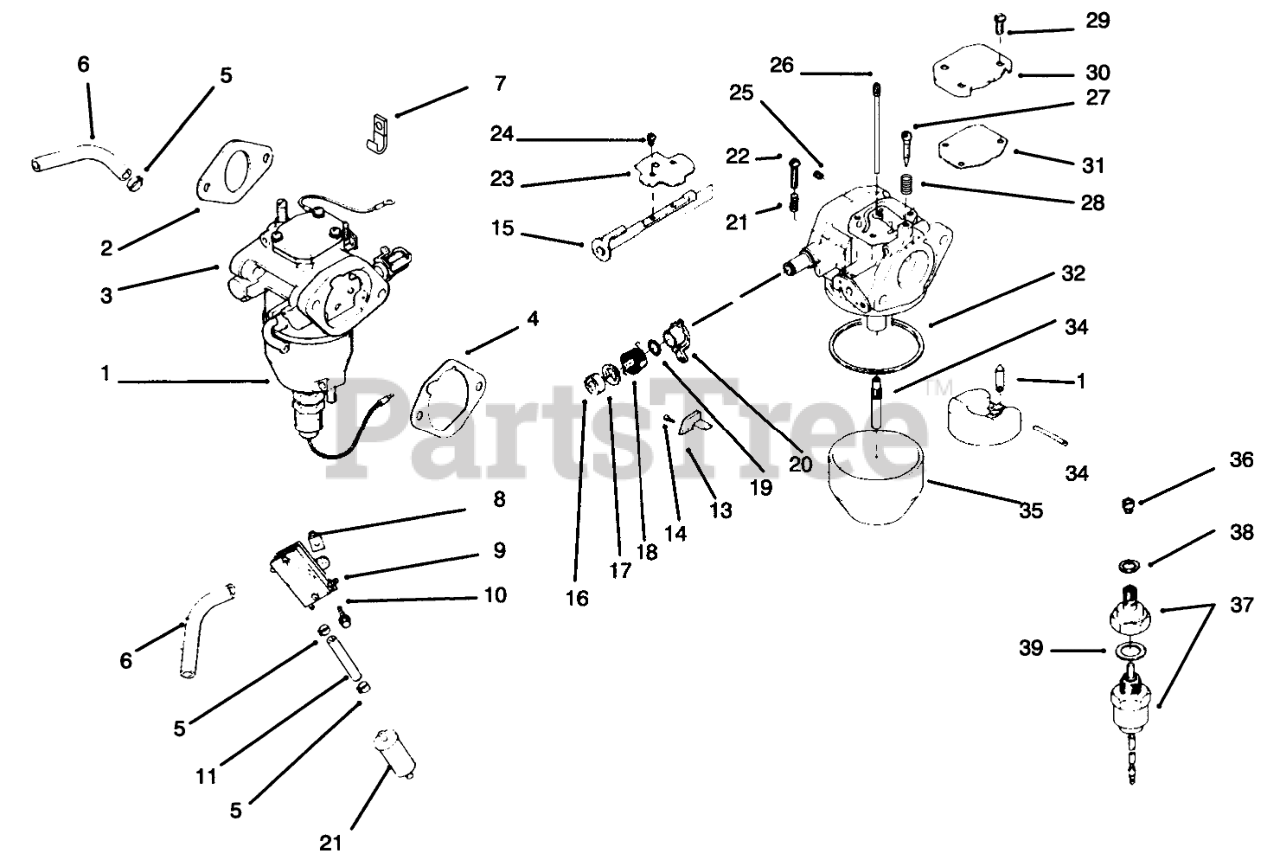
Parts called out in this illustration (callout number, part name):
1	Kit-Carburetor (Incl. Ref.#2-4)
2	Kit-Carburetor
3	Carburetor (Ref. Only) (Inc. Ref.15-39)
4	Gasket-A/C Base
5	Clamp-Hose
6	Line-Fuel 12"
7	Clamp
8	Nut
9	Pump-Fuel
10	Screw
11	Line-Fuel
12	Filter-Fuel
13	Bracket-Throttle Stop
15	Shaft-Choke
16	Washer
17	Collar-Coke
18	Spring-Choke Return
19	Ring-Choke Lever
20	Lever-Choke
21	Sprin-Throttle Screw
22	Screw-Throttle Adjust
23	Valve-Choke
24	Screw
25	Jet-Air Bleed
26	Jet-Slow
27	Screw
28	Spring-idler Screw
29	Screw
30	Cover-Passage
31	Gasket-Passage Cover
32	Gasket-Float Chamber
33	Kit-Float Repair
34	Nozzle-Main
35	Chamber-Float
36	Jet-Main
37	Kit-Solenoid Valve (Incl. Ref. #38-39)
38	Gasket-Chamber Screw
39	Gasket-Solenoid
